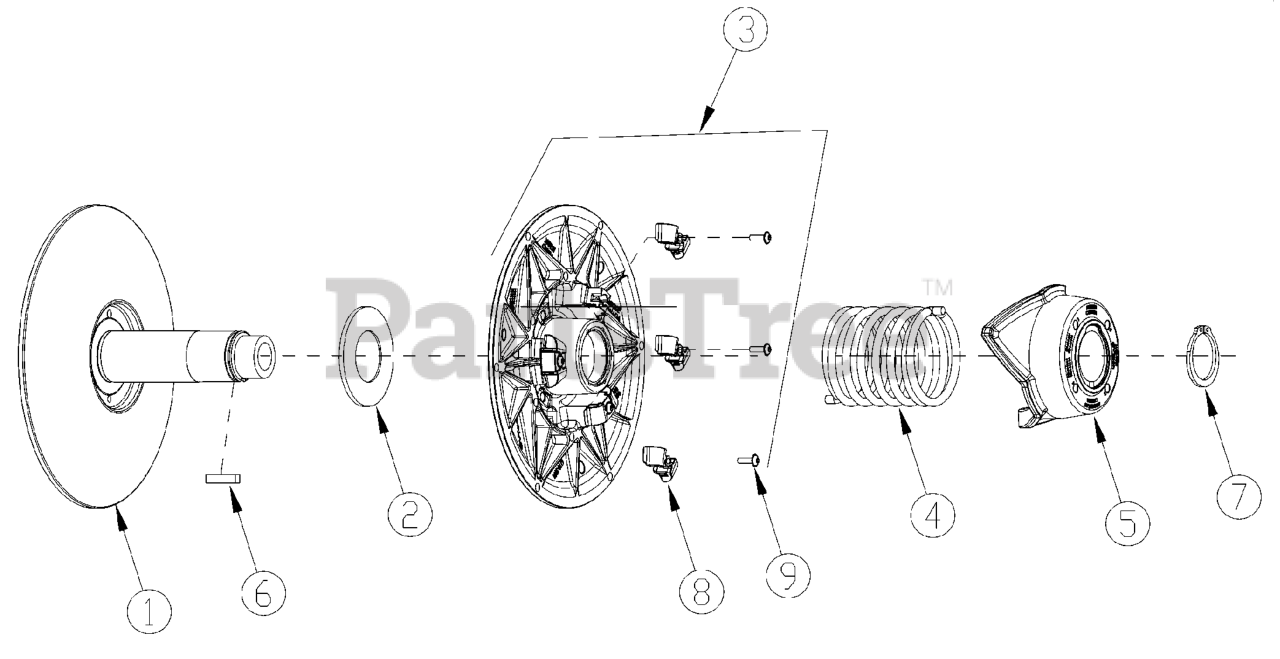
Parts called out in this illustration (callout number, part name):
1	FIXED FLANGE
2	SHIM WASHER
3	SLIDING FLANGE
4	SPRING
6	SQUARE KEY 1/4
7	SNAP RING
8	CAM SHOE
9	HEX, SOCKET BUTTON HEAD
